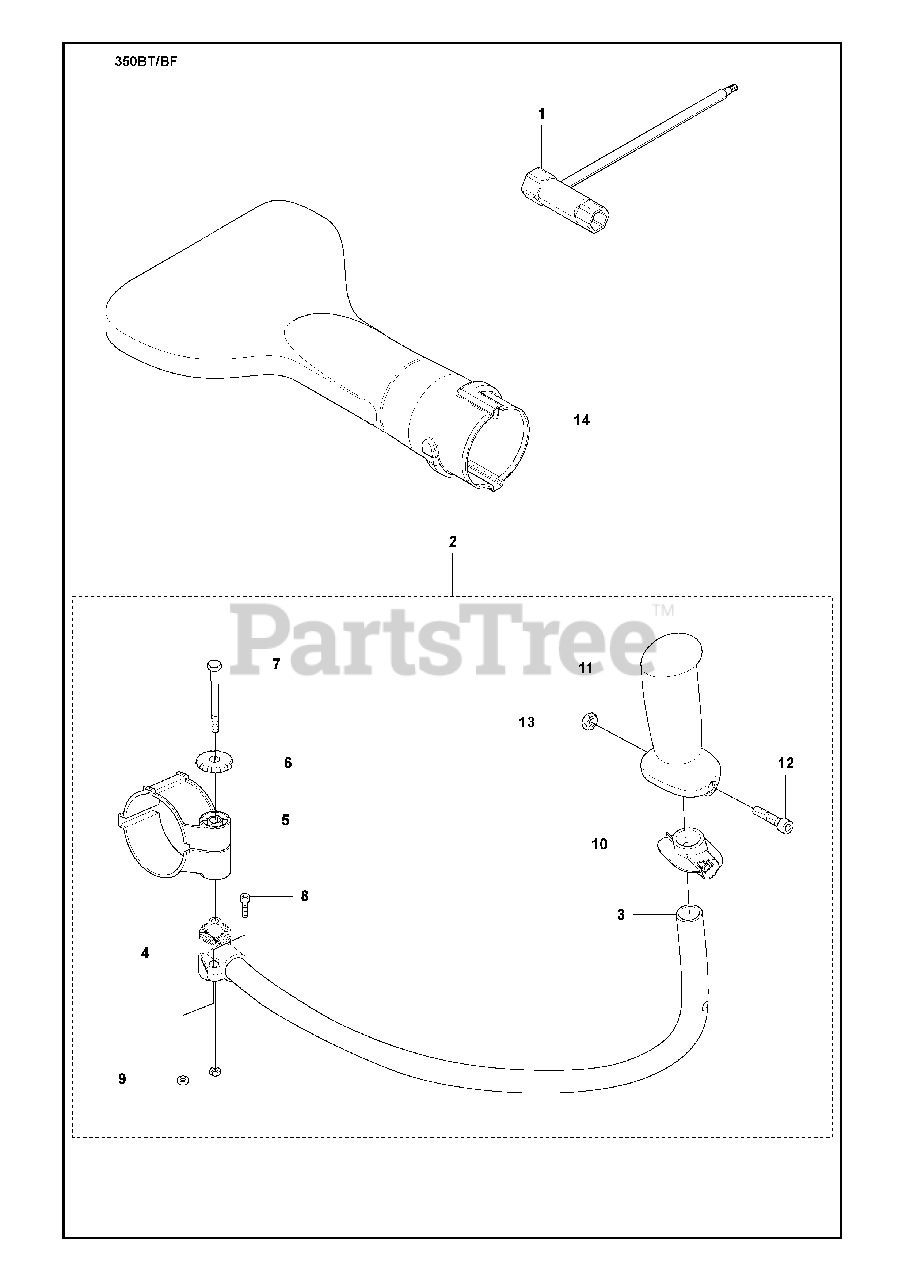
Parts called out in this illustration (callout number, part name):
1	SOCKET
2	HANDLEBAR ASSY
5	HOLDER TH
8	SCREW MC6S 5X10
14	FLAT NOZZLE
